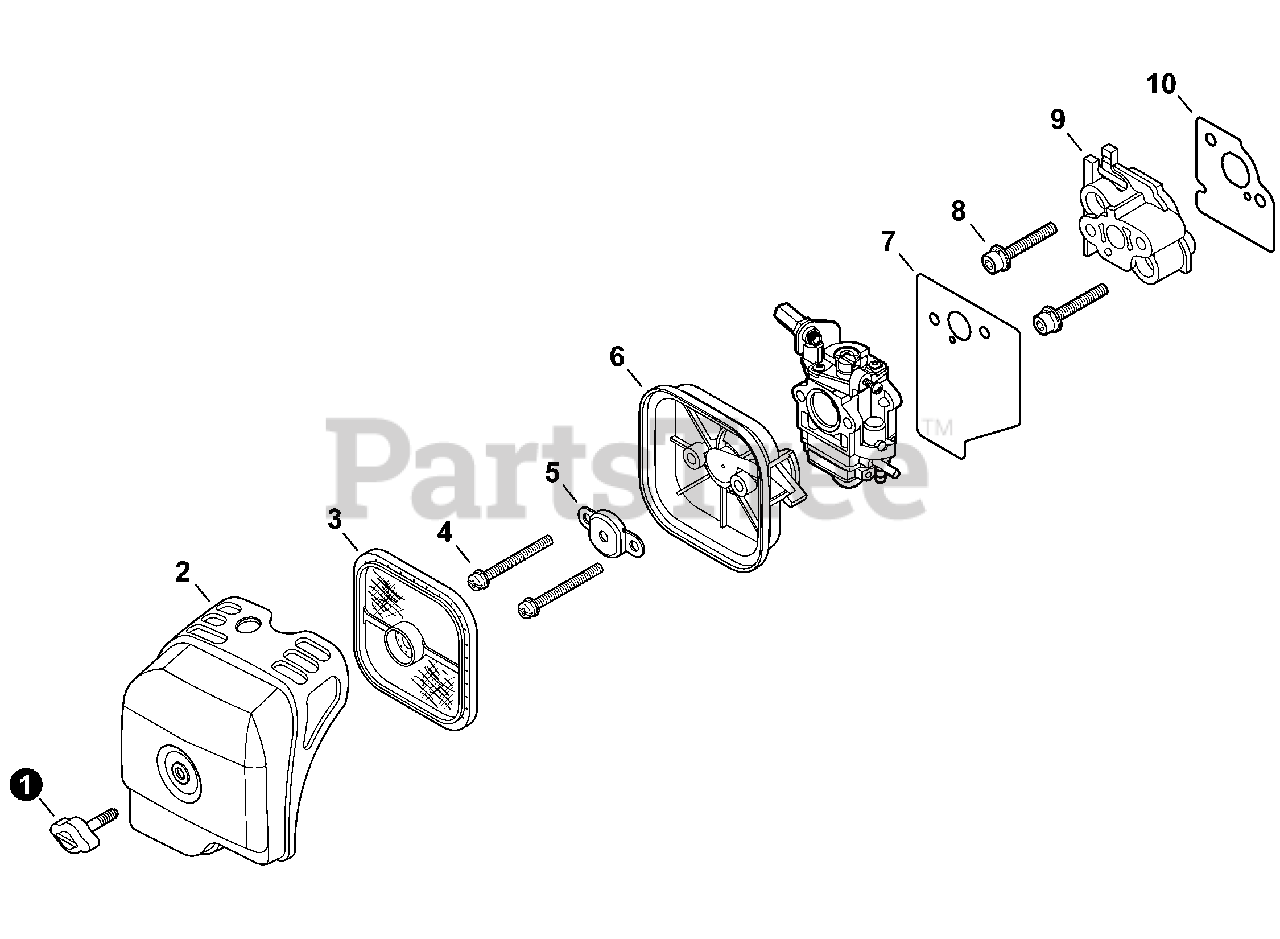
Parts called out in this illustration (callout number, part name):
1	THUMBSCREW
2	COVER, AIR FILTER
3	FILTER, AIR - DOUBLE LAYER
4	SCREW 5×60
5	PLATE, PREVENT
6	CASE ASSY, AIR FILTER
7	GASKET, CARBURETOR
8	BOLT M5×30
9	INSULATOR
10	HEAT SHIELD, INTAKE
